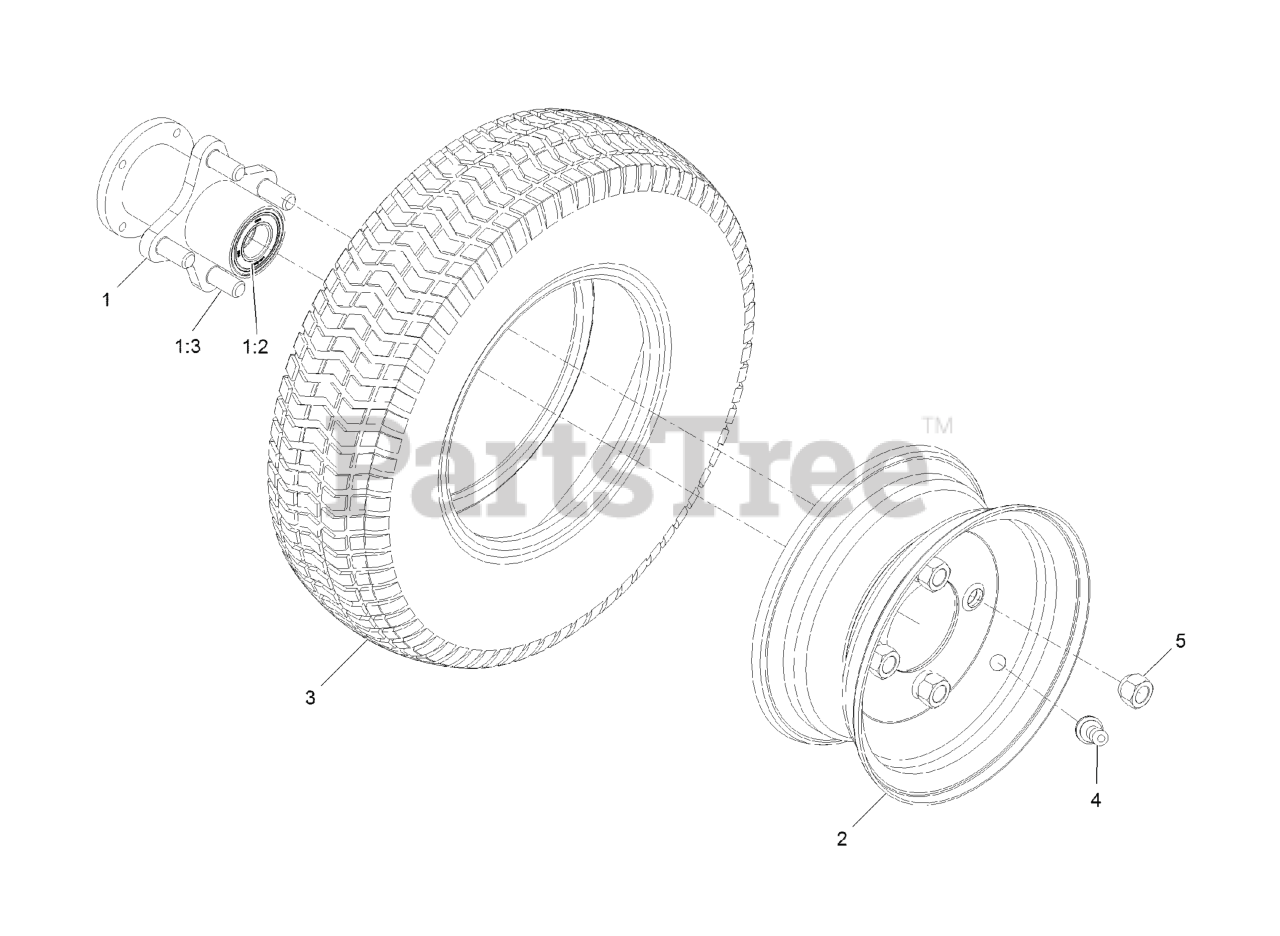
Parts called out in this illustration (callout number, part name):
1	Wheel Hub ASM
1:2	BEARING-BALL
1:3	STUD-TYPE, DRIVE
2	Rim
3	Tire
4	Stem-Valve
5	NUT-LUG
